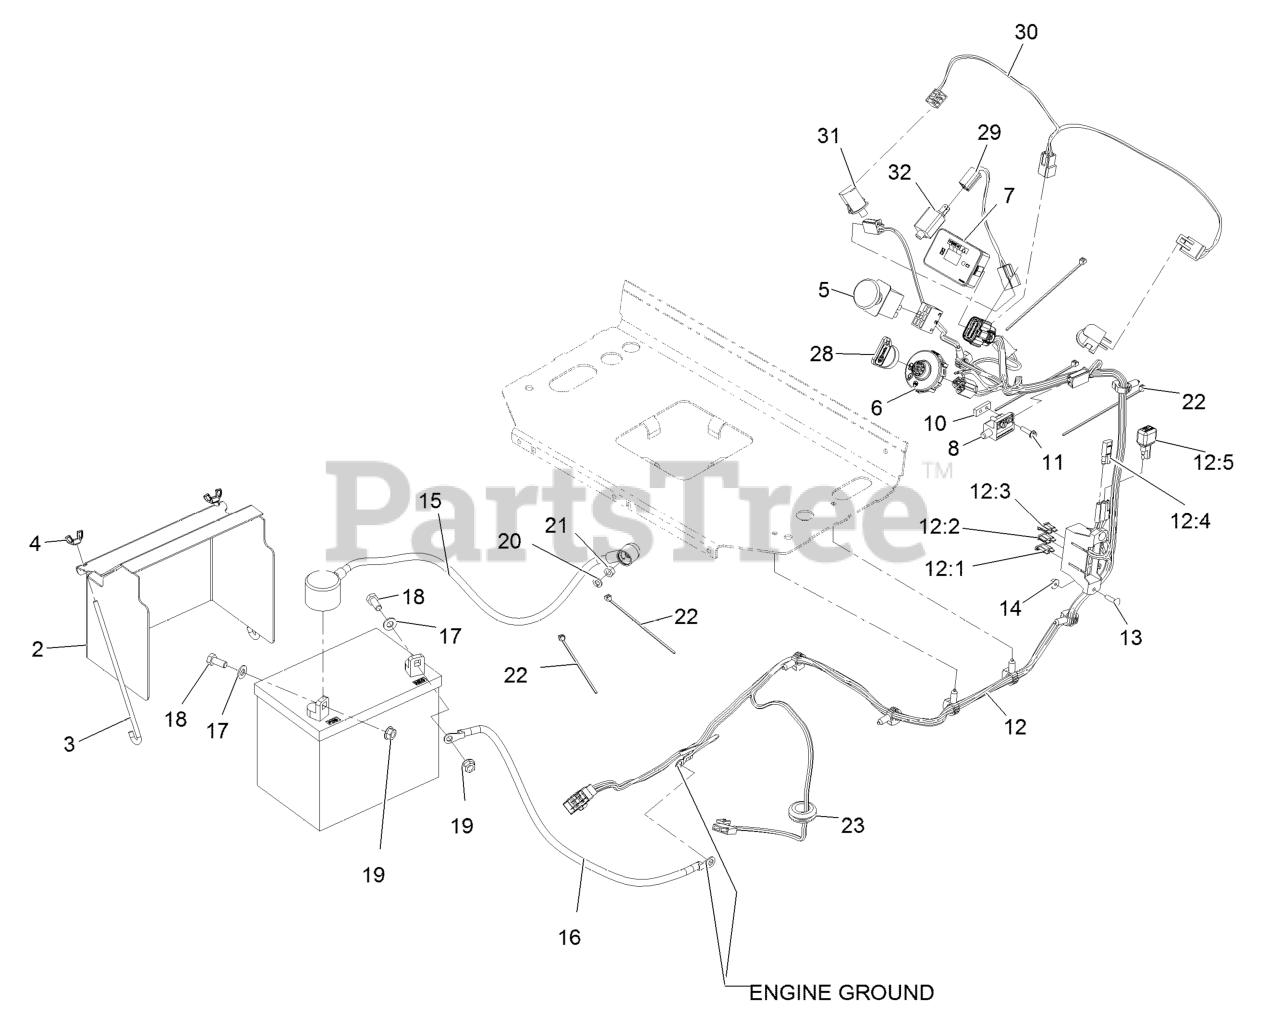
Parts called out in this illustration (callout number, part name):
2	COVER-BATTERY
3	BOLT-HOLDDOWN
4	WINGNUT
5	SWITCH-PTO, ON-ON
7	MODULE-HOUR METER
8	SWITCH-CLOSED, NORMALLY
10	PLATE-TAPPED
11	SCREW-HWH
12	HARNESS-WIRE
12:1	FUSE-BLADE, 30 AMP
12:2	FUSE-BLADE, 25 AMP
12:3	FUSE-BLADE, 10 AMP
12:4	CAP-PLUG
13	SCREW-CARR
15	CABLE-BATTERY, POSITIVE
16	CABLE-BATTERY, BLACK
17	WASHER-PLAIN
18	SCREW-HH
19	NUT-HHF, SMOOTH
20	SCREW-HH
21	NUT-HEX
22	TIE-CABLE
23	GROMMET
28	KEY-IGNITION
29	HARNESS-NEUTRAL
30	HARNESS-OPC
31	SWITCH-BAIL
32	SWITCH-OPEN, NORMALLY
